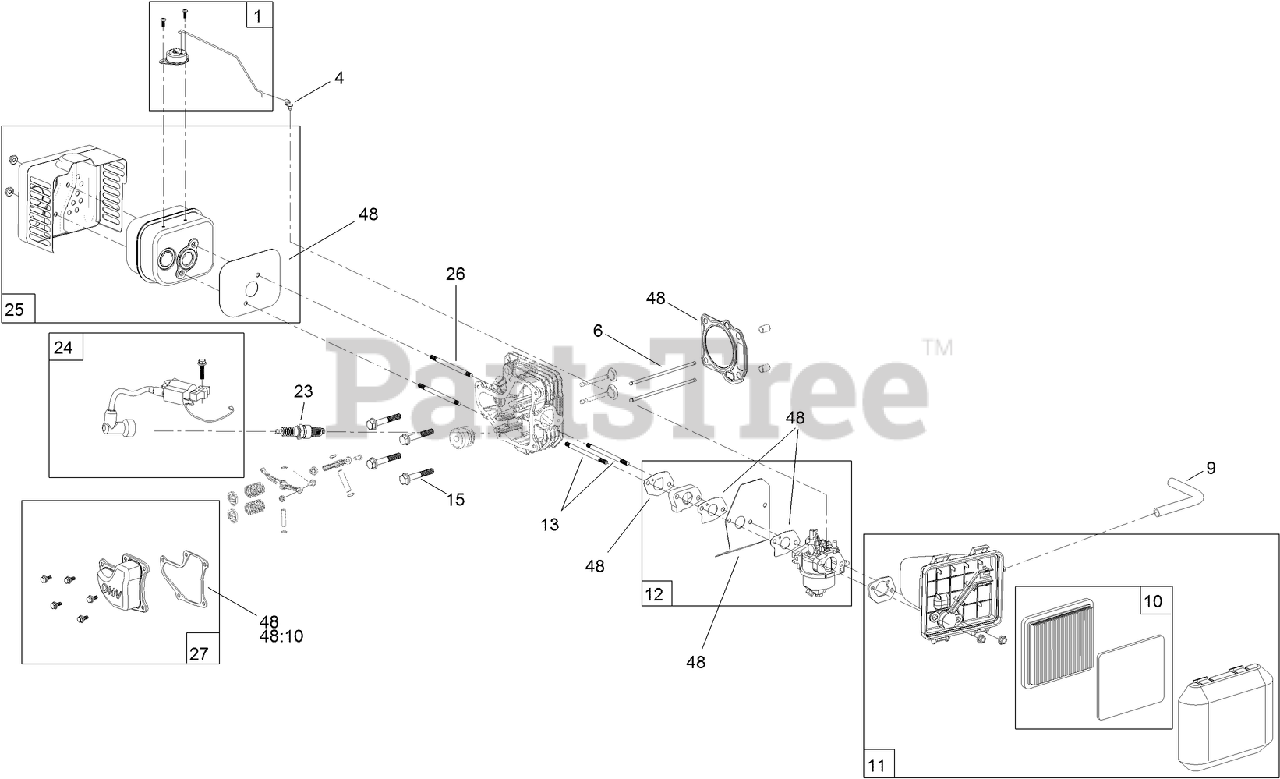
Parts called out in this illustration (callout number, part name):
1	THERMAL CONTROL KIT
4	LOCK-THROTTLE
6	ROD-PUSH
9	TUBE-BREATHER
10	AIR FILTER AND PREFILTER KIT
11	AIR CLEANER ASM KIT
12	INTERNAL CARB KIT WITH GASKETS
13	STUD-INTAKE
15	BOLT-FLANGE
23	SPARK PLUG
25	MUFFLER AND SHIELD KIT
26	STUD-EXHAUST
27	VALVE COVER KIT
48	SEAL AND GASKET KIT
48:10	GASKET-VALVE COVER
